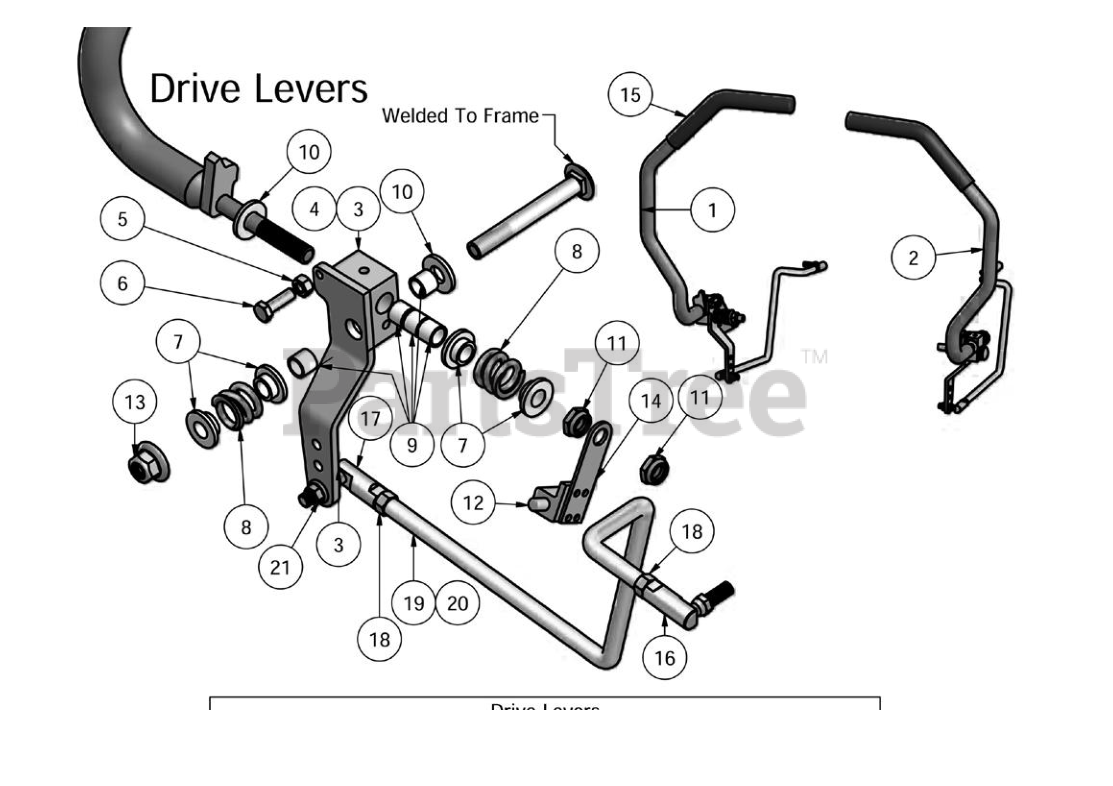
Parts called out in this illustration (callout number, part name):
1	Right Drive Lever
2	Left Drive Lever
3	Drive Arm Lever Housing - Right
4	Drive Arm Lever Housing - Left
6	5/16" x 3/4" Bolt
7	Nylon Washer .515 ID Shoulder
9	Nylon Bushing .507 ID
10	.505 Nylon Washer
11	1/2" Nylock (1/2 Jam)
12	Electric Saftey Switch
13	1/2-13 Nylon Flange Nut-Orange
14	Switch Bracket
15	Rubber Grip
16	3/8-24 Ball joint (female/male)
17	3/8-24 Ball Joint
18	3/8" Fine Threaded Jam Nut
19	Transaxle Drive Rod (Right)
20	Transaxle Drive Rod (Left)
21	5/16" Flange Nut
